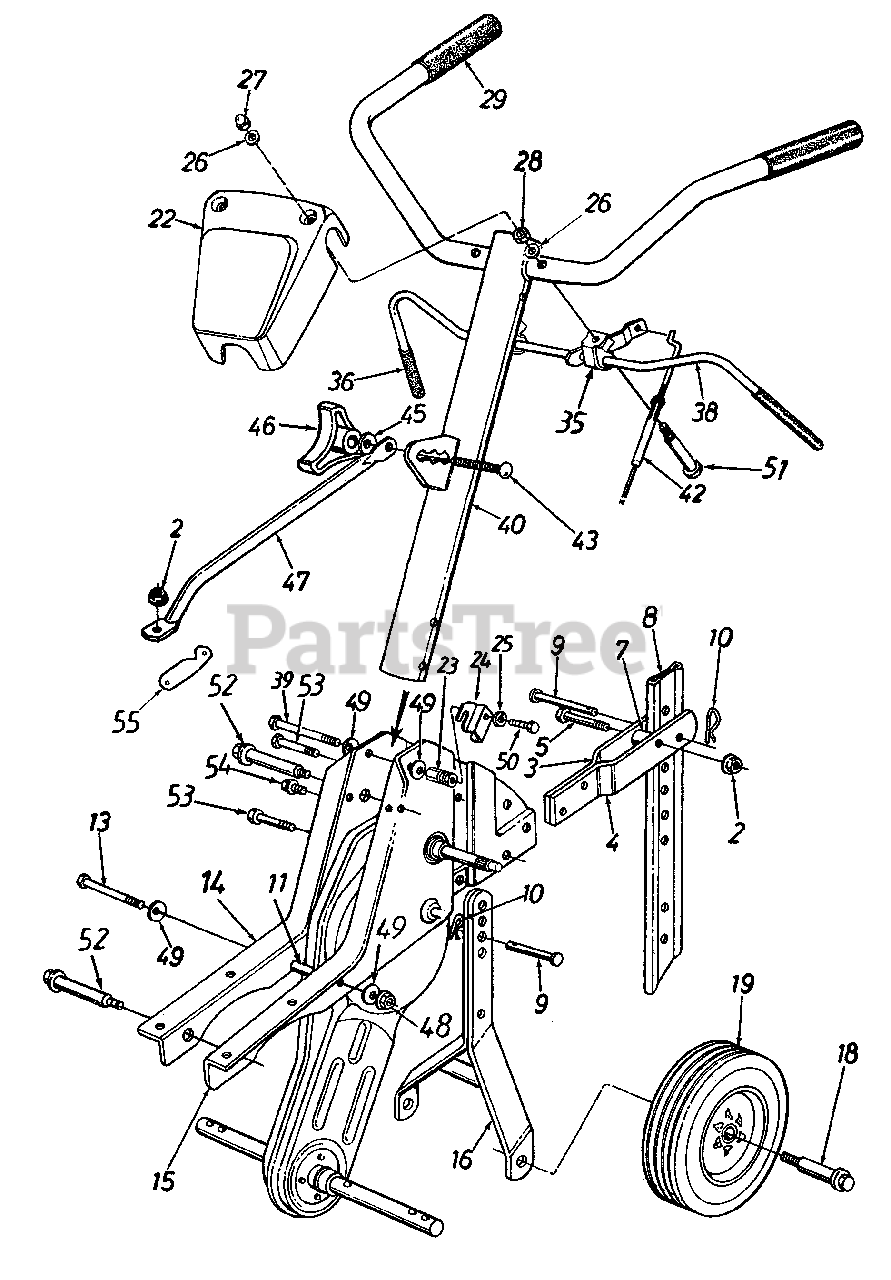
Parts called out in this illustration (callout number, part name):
2	Hex Flange L-Nut 5/16-18 Thd. (Gr. 5)
4	Tail Piece Brkt. (L.H.)
5	Hex Bolt 5/16-18 x 1.5" Lg.
7	Spacer .32" I.D. x .75" O.D.
9	Clevis Pin .375" I.D. x 1.62" Lg.
10	Internal Cotter Pin
11	Spacer .326" I.D. x .47" O.D.
13	Hex Bolt 5/16-18 x 2.75" Lg.
14	Frame - R.H.
15	Frame - L.H.
18	Shld. Bolt .498" Dia. x 1.45" Lg.
19	Wheel Ass'y.
22	Handle Cover
23	Spec. Hex Nut
25	L-Wash. 5/16" I.D.
26	Fl-Wash. .266" I.D. x .625" O.D.
27	Hex L-Stop Nut 1/4-28 Thd.
28	Hex Nut 1/4-20 Thd.
29	Grip - Handle
35	Clutch Handle Holder
36	Grip - Clutch
39	Hex Bolt 5/16-18 x 3" Lg.
40	Longhorn Handle Ass'y.
42	Clutch Control Cable
43	Carr. Bolt 5/16-18 x 1" Lg. (Special)
45	Wash. Bell. .340' I.D. x .872 O.D.
46	Hand Knob
47	Engine Tubing Brace
48	Hex L-Nut 5/16-18 Thd.
49	Bell-Wash. .345" I.D. x .88" O.D.
50	Hex Bolt 5/16-18 x .75" Lg. (Gr. 5)
51	Hex Bolt 1/4-20 x 2.25" Lg.
52	Shld. Bolt
53	Hex Wash. Hd. TT-Tap Scr. 5/16-18 x .62" Lg.
54	Hex Wash. Hd. TT-Tap Scr. 5/16-18 x 1"Lg.
55	Engine Bracket
